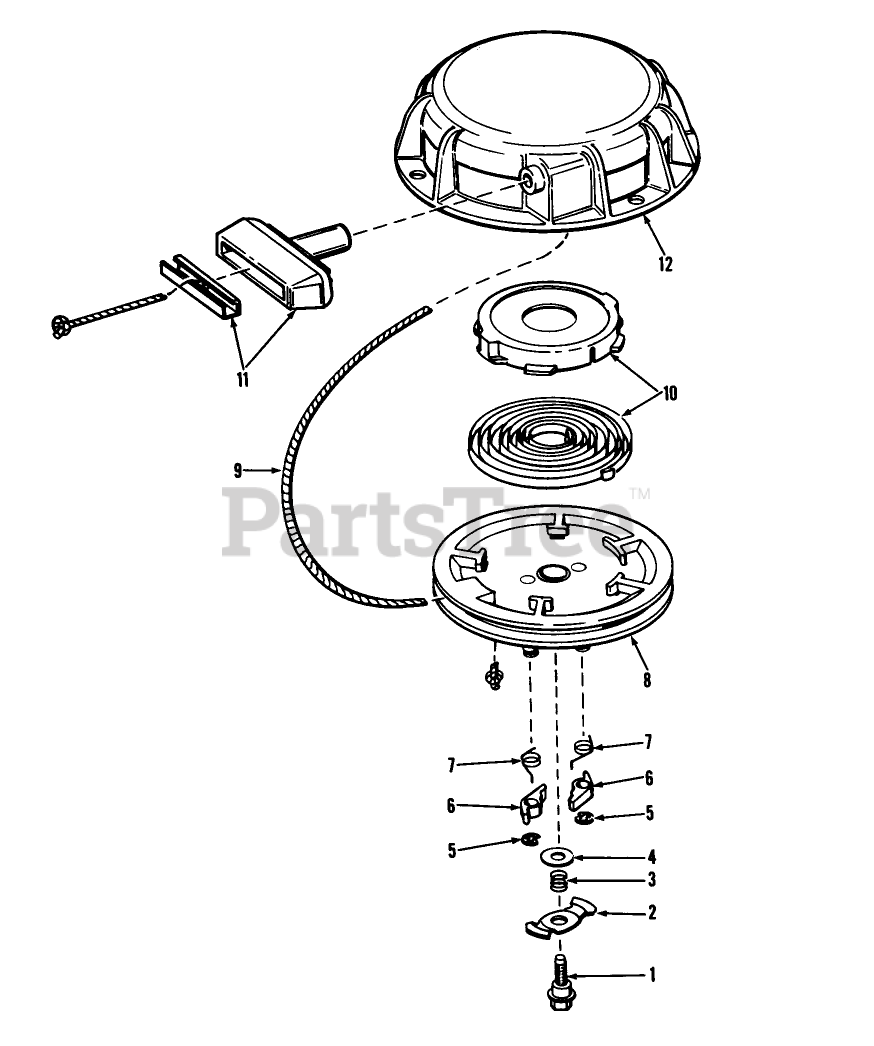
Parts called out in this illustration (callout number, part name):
1	Screw, Center
2	Cam, Dog
3	Spring, Brake
4	Washer, Brake
5	Ring, Retainer
7	Spring, Dog
8	Pulley
9	Rope-Starter
10	Spring & Keeper Assy.
11	Assy., Starter
12	Housing Assy., Starter
